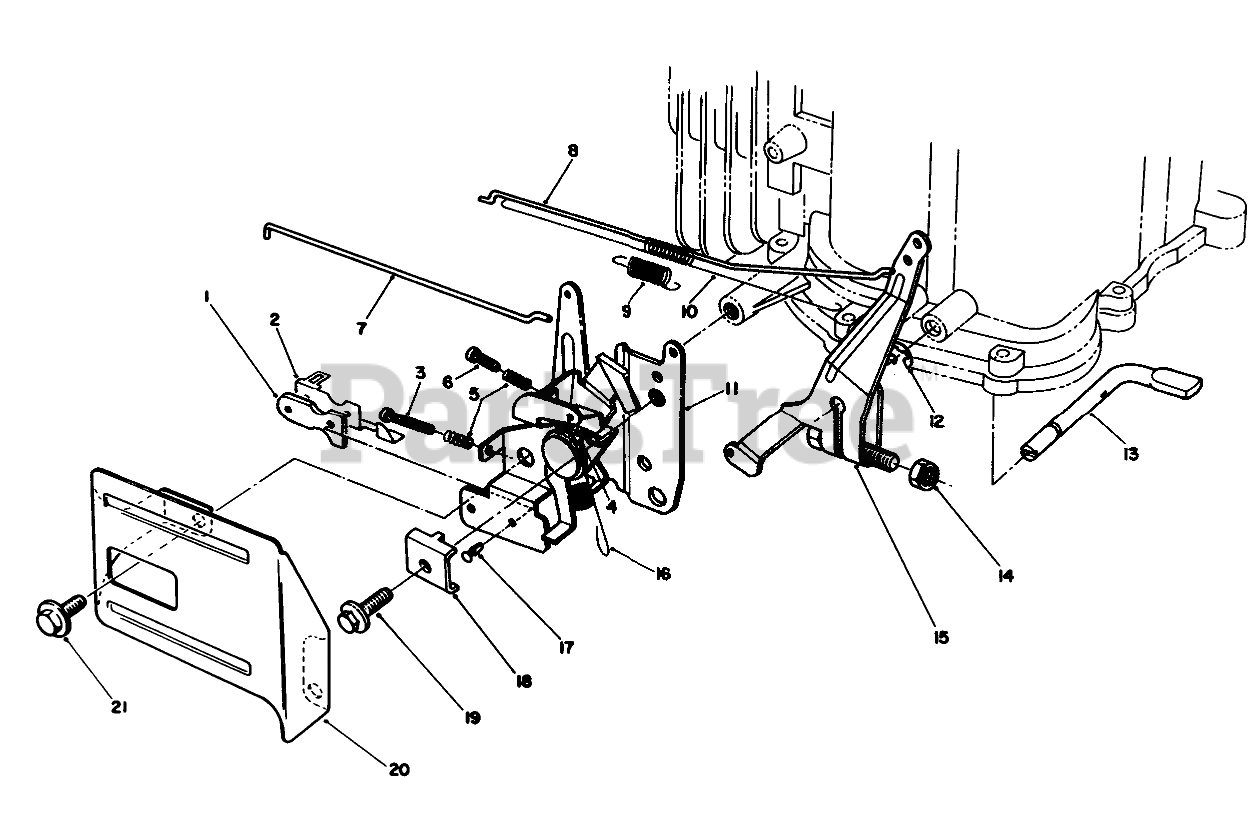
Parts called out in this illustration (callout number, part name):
1	INSULATOR-KILL SWITCH
2	TERMINAL-KILL SWITCH
3	SCREW
4	SPRING
5	SPRING
6	SCREW
7	Rod-Choke
8	Rod-Carburetor
9	SPRING
10	SPRING
11	THROTTLE
12	E-RING
13	SHAFT
15	ARM ASM
16	SPRING
17	RIVET
18	CLAMP-CABLE
20	THROTTLE GUARD
